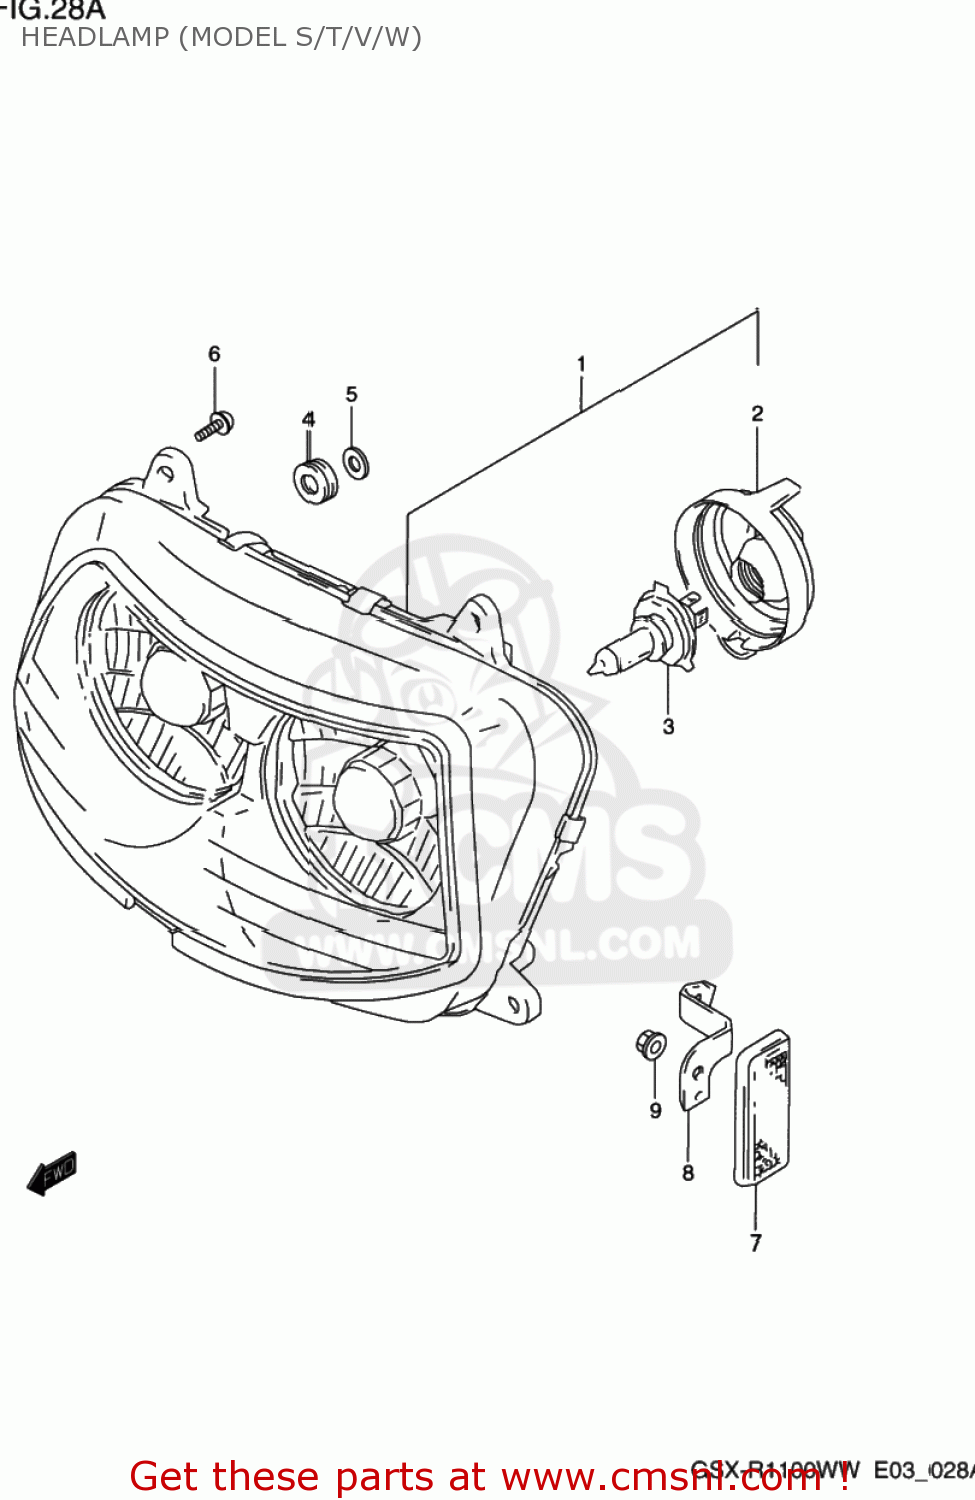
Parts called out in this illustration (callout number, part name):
1	HEADLAMP ASSEMBLY
2	COVER,SOCKET
3	BULB(12V60/55W,H4)
4	CUSHION
5	WASHER(5.5X16X1.2)
6	SCREW,SIDE HOL
7	REFLEX REFLECTOR,FR SIDE
8	BRACKET,FR SIDE RR,R
9	NUT
